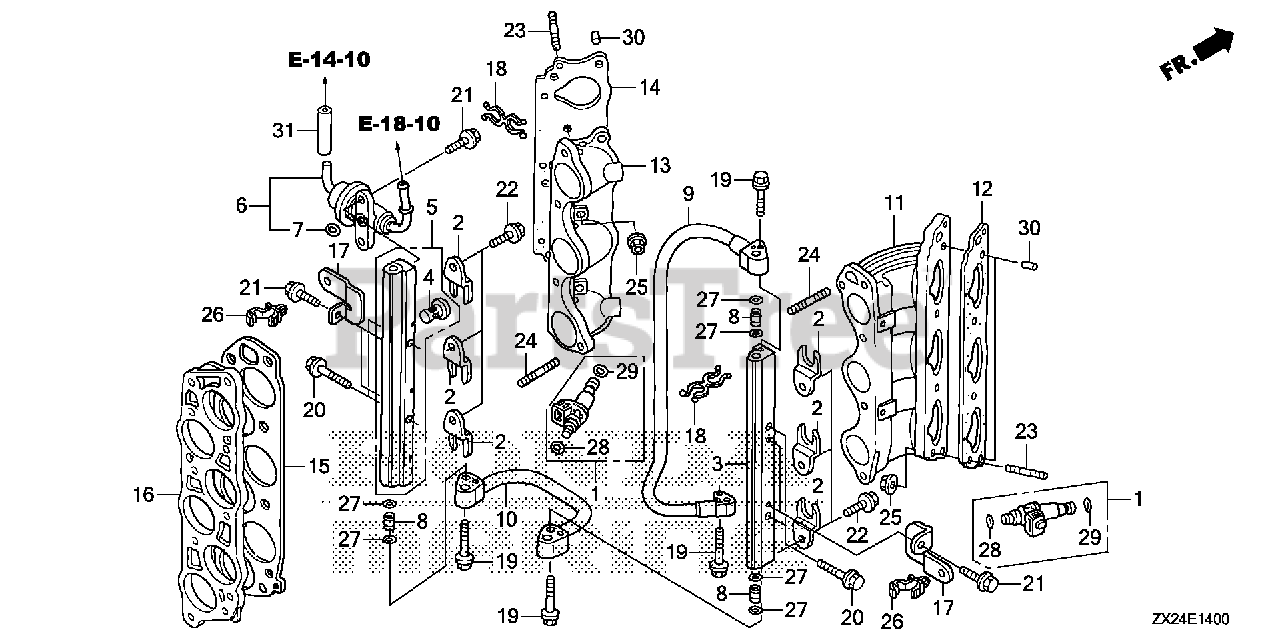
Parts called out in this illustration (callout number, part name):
1	INJECTOR ASSY., FUEL
2	CLIP, INJECTOR
3	PIPE, R. FUEL
4	MESH, FUEL FILTER
5	PIPE, L. FUEL
6	REGULATOR ASSY., PRESSURE
7	O-RING, PRESSURE REGULATOR
8	JOINT, FUEL PIPE
9	HOSE, FUEL
10	HOSE, FUEL JOINT
11	BASE, R. INJECTOR
12	GASKET, FR. INJECTOR BASE
13	BASE, L. INJECTOR
14	GASKET, RR. INJECTOR BASE
15	GASKET, IN. MANIFOLD
16	SPACER, IN. MANIFOLD
17	BRACKET, HARNESS CLIP A
18	CLIP D, SPEEDOMETER CABLE
19	BOLT, FLANGE (6X25)
20	BOLT, FLANGE (6X35)
21	BOLT, FLANGE (6X14)
22	BOLT, FLANGE (6X10)
23	BOLT, STUD (8X28)
24	BOLT, STUD (8X45)
25	NUT, FLANGE (8MM)
26	CLIP, WIRE HARNESS (10MM)
27	O-RING (7.8X1.9) (ARAI)
28	O-RING (7.47X3.6)
29	O-RING (7.45X3.61) (NOK)
30	PIN, DOWEL (10X12)
31	BULK HOSE, FUEL (3.5X3000) (3.5X50)
